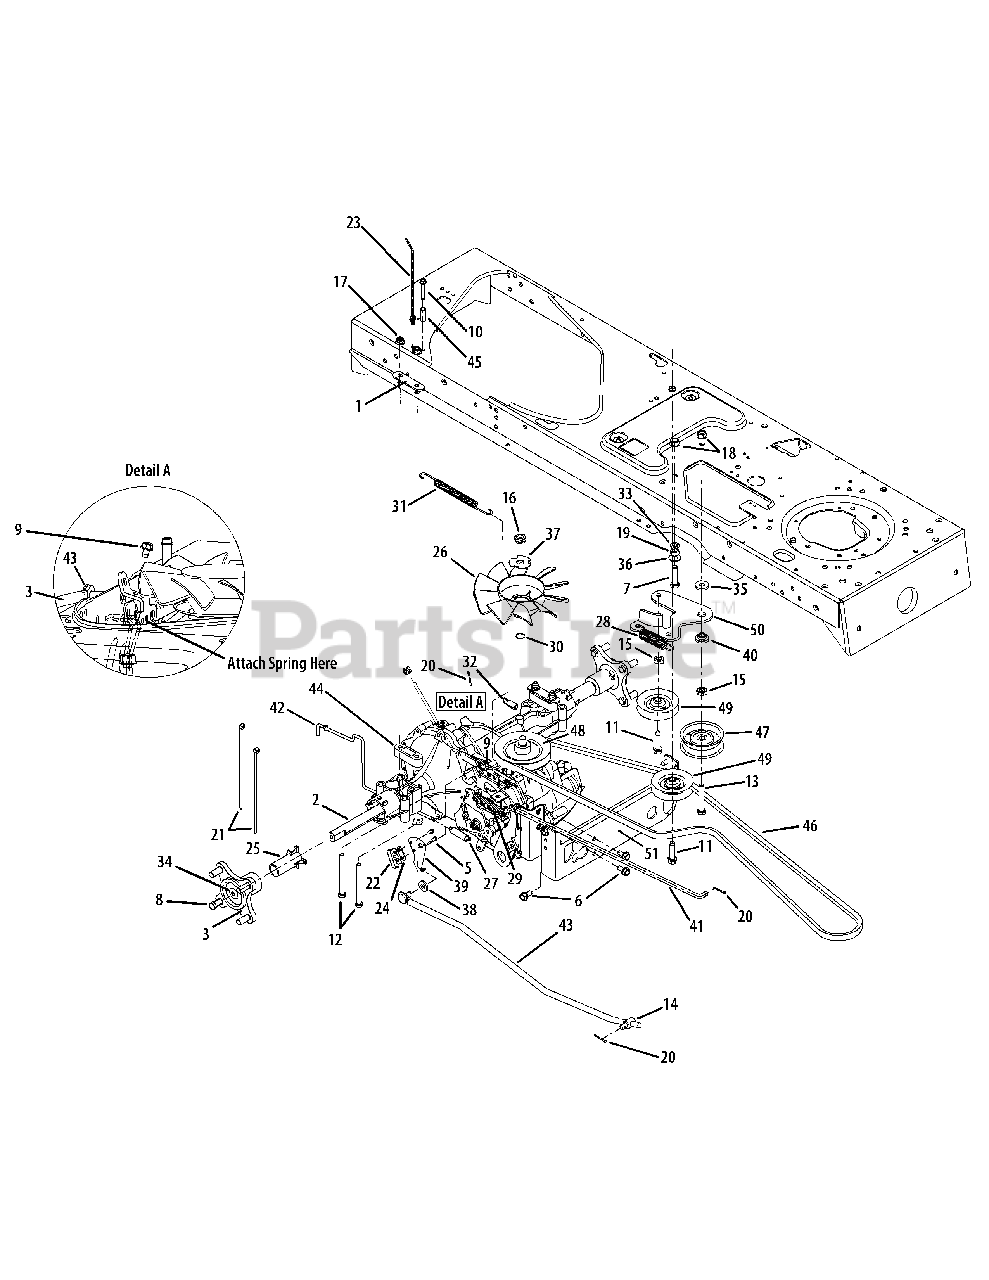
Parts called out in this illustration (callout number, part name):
2	Transmission, Hydrostatic
3	Hub Assembly, Wheel
4	Harness Assembly, Grnd. & Rev.
5	Screw, #8-18, 0.500
6	Screw, 5/16-12, 0.75
7	Hex Cap Screw, 3/8-16, 1.50, Gr5
8	Hex Cap Screw, 5/16-24 x .750
9	Screw, 1/4-20 x .375
10	Hex Cap Screw, 1/4-20, 1.5, Gr5
11	Screw, 3/8-16, x 1.50
12	Hex Cap Screw, 5/16-18,3.5, Gr5
13	Hex Cap Screw, 3/8-16, 2.25, Gr5
14	Ferrule, 3/8-24 x .375 Dia
15	Nut, Jam, 7/16-20, Gr2
16	Nut, Jam Lock, 1/2-20, Gr5
17	Nut, Hex Nylon Lock, 5/16-18
18	Nut, Flange Lock, 3/8-16
19	Nut, Hex, 3/8-16, Gr8
20	Pin, Cotter, 3/32, 1.0
21	Cable, Tie, 3/16 x .05 x 7.4
22	Switch, Spring, Short
23	Tie, Cable, Push Mount 7.5 Lg
24	Plate, Insulator Nut
25	Sleeve, 2.4"
26	Fan, Blade
27	Spring, .48 OD x 2.03 Extension
28	Spring, Extension, .563 Dia x 3.72 Lg
29	Spring, Extension, .59 OD x 4.00 Lg
30	Ring, Wire
31	Spring, Extension, .500 Dia x 7.0
32	Spring, Extension, 3/8 OD x 1.44
33	Washer, Lock, 3/8, Regular Duty
34	Bell Washer
35	Washer, Flat, .385 x 1.0 x .135
36	Washer, Flat, .406 x .875 x .059
37	Washer, Lock, Hydro
38	Washer, Flat, .407 x .812 x .135
39	Bracket, Actuator, Switch
40	Spacer, Shoulder, 1.00 x .38 x .38
41	Rod, Brake, Hydro
42	Rod, Hydro Bypass
43	Rod, Control, Hydro
44	Spacer, T-axle .68
45	Spacer, 1"
46	Belt, V Type, Poly
47	Pulley, Idler, Flat 2.75 OD
48	Pulley, Engine, 4.13 Dia.
49	Pulley, Idler, V Type x 3.06 Dia
